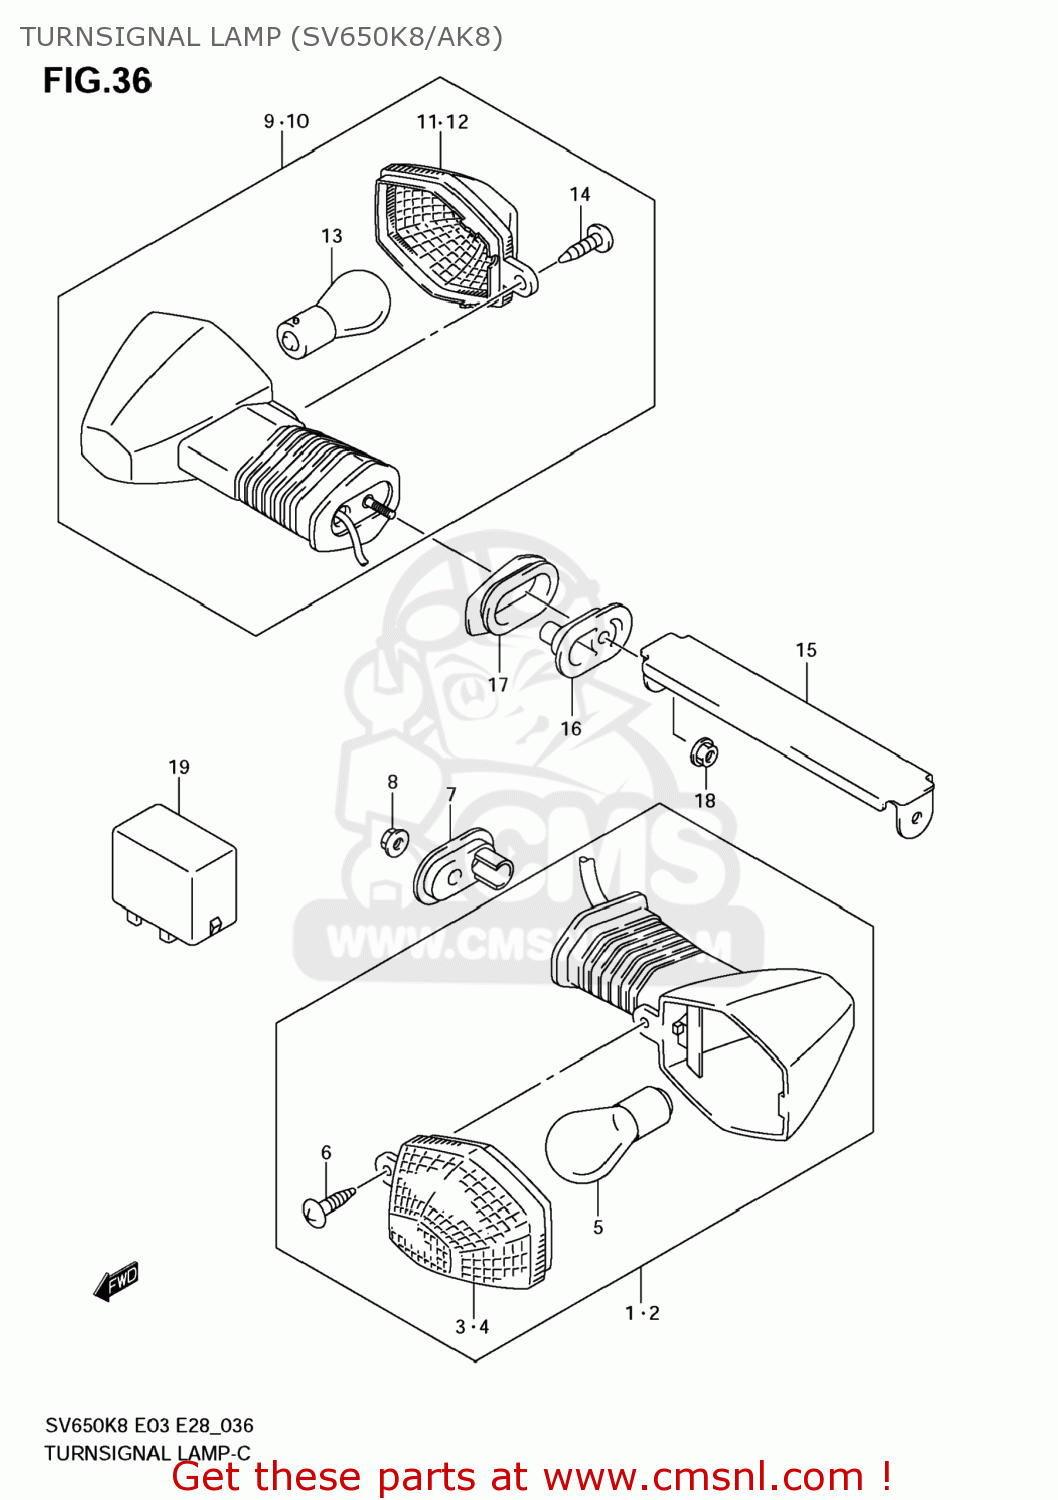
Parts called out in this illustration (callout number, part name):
1	LAMP ASSY,FR TURN SIGNAL,R
2	LAMP ASSY,FR TURN SIGNAL,L
3	LENS
4	LENS
5	BULB(12V21W)
6	SCREW
7	PLATE,TURNSIGNAL LAMP
8	NUT
9	LAMP ASSY,RR TURNSIGNAL,R
10	LAMP ASSY,RR TURNSIGNAL,L
11	LENS
12	LENS
13	BULB(12V21W)
14	SCREW
15	BRACKET,RR TURNSIGNAL
16	PLATE,RR TURN SIGNAL
17	CUSHION,RR
18	NUT
19	RELAY ASSY,TURNSIGNAL LAMP
